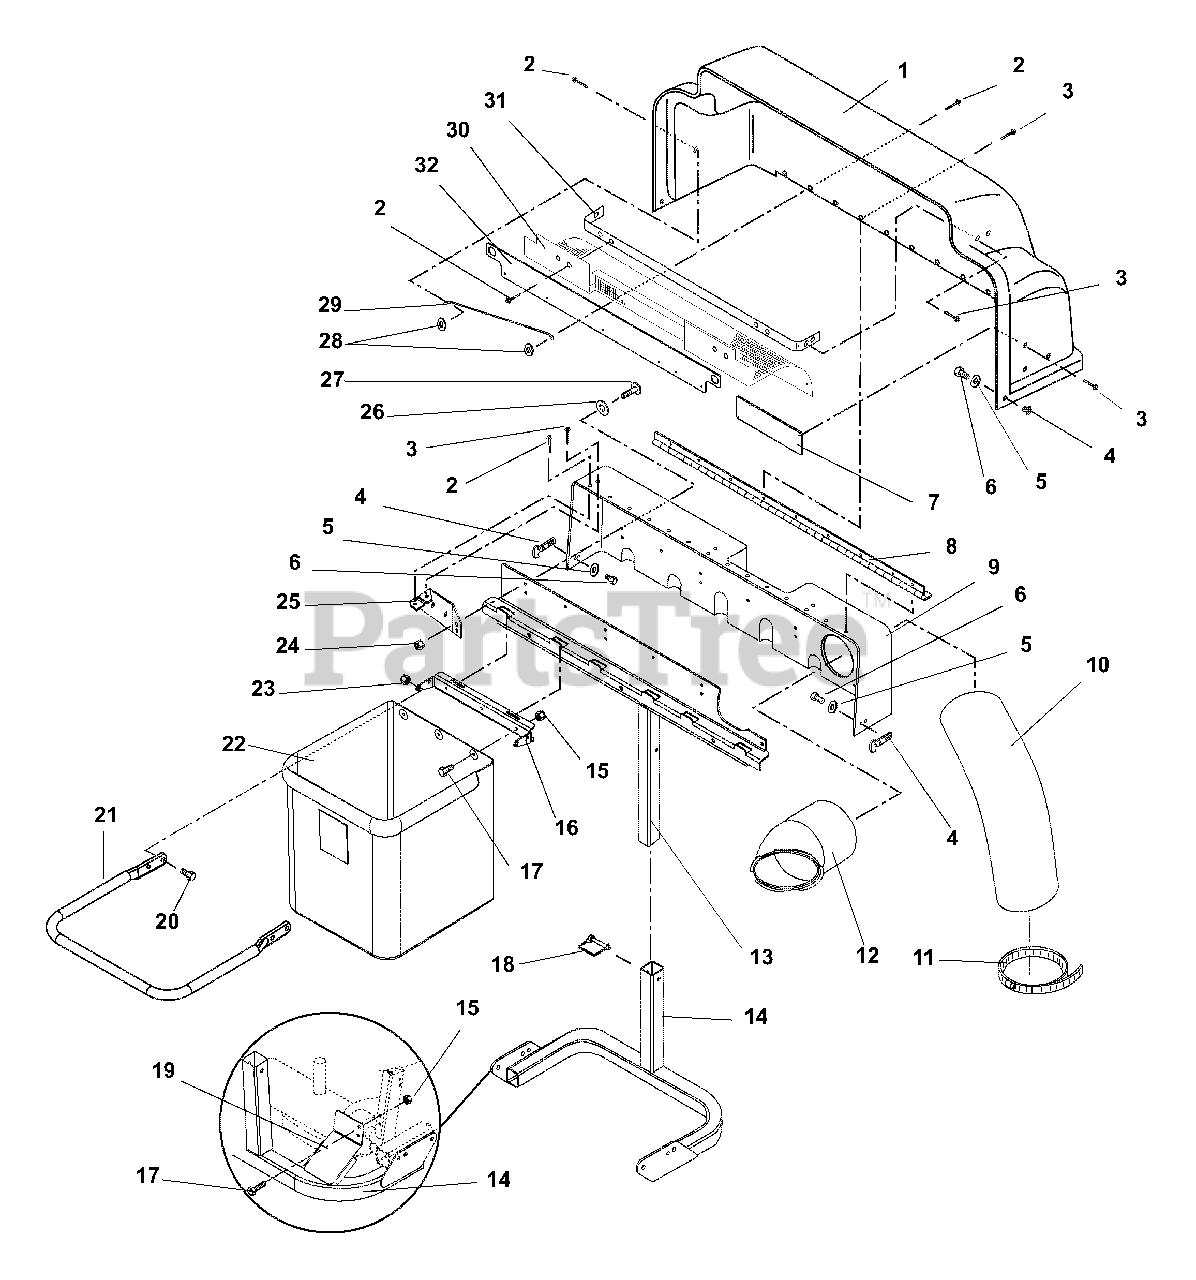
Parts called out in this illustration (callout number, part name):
1	Hinged Cover with Decal
2	Rivet-Pop .187 x .527
2	(Gravely Part Number)
3	Rivet-Pop .187 x .402
4	Latch, Rubber
5	Washer-Flat-Steel .219 x .50 x .049
6	Screw-Machine 10-24 x .50 Hex Washer Head
9	Stationary Cover
9	(Gravely Part Number)
10	Hose 7 x 45
11	Clamp-Hose Worm 2.13/8.62 x .56
11	(Gravely Part Number)
12	Bagger Boot- Upper
12	(Gravely Part Number)
13	Weldment-Bagger Frame
14	Weldment-Bumper
15	Nut-Locking-Center .25-20
16	Clamp-Bag
17	Bolt-Hex .25-20 x .50 Grade 5
18	Pin-.38 x 2.50 Square Lock
19	Deflector, Exhaust
20	Bolt-Round Head Square Short Neck .31-18 x .75 Grade 5
21	Frame-Bag Support
22	Bag-Mesh Assist Bagger
23	Nut-Spin Lock-Flange .312-18
24	Nut- Locking-Nylon .312-18 Grade 2
25	(Gravely Part Number)
26	Washer-Flat-Steel .344 x .063
27	Bolt-Hex .31-18 x 1.00 Grade 2
28	Washer-Flat-Steel .219 x .50 x .049
29	(Gravely Part Number)
31	Screen Mounting Bracket
32	Guard, Screen
